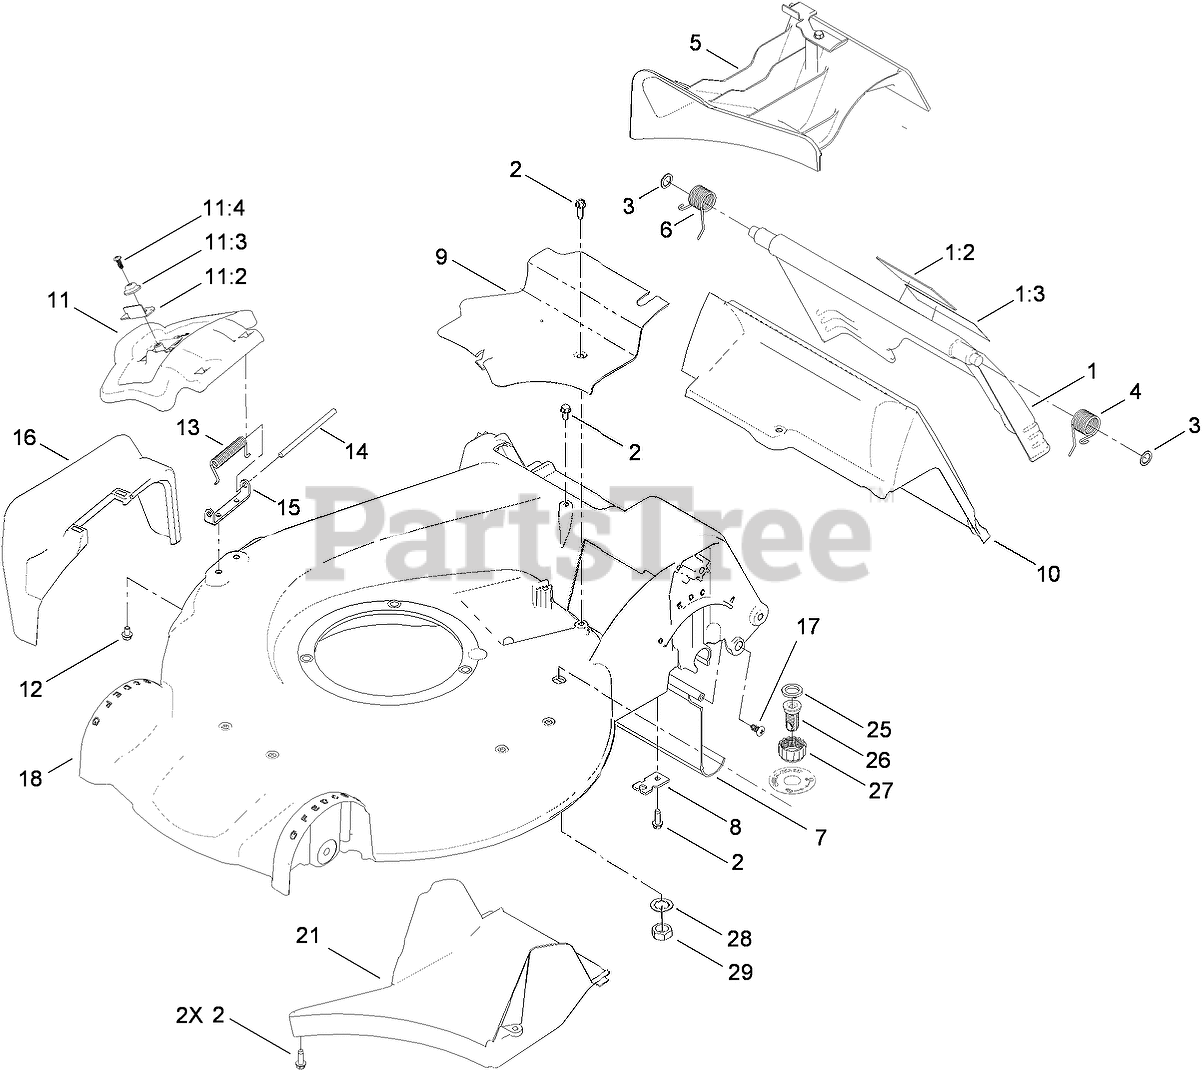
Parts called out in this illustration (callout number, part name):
1	REAR DOOR ASM
1:2	DECAL-WARNING
1:3	DECAL-WARNING
2	SCREW-HWHTF
3	WASHER-NYLON
4	SPRING-TORSION
5	MULCH PLUG ASM
6	SPRING-TORSION
7	SHIELD-TRAILING
8	BRACKET-CABLE, TRACTION
9	COVER-BELT
11	DISCHARGE DOOR ASM
11:2	LATCH-DOOR
11:3	CAP-DOOR
11:4	SCREW-PLASTITE
12	SCREW-HWH
13	SPRING-TORSION
14	ROD-COVER
15	BRACKET-COVER
16	CHUTE-DISCHARGE, SIDE
17	SCREW-PTH
18	HOUSING ASM
21	TUNNEL-DISCHARGE
25	WASHER-SEAL, WASHOUT PORT
26	PORT-WASHOUT
27	COUPLING-HOSE, WASHOUT PORT
28	WASHER-TOOTH, INTERNAL
29	NUT-JAM
